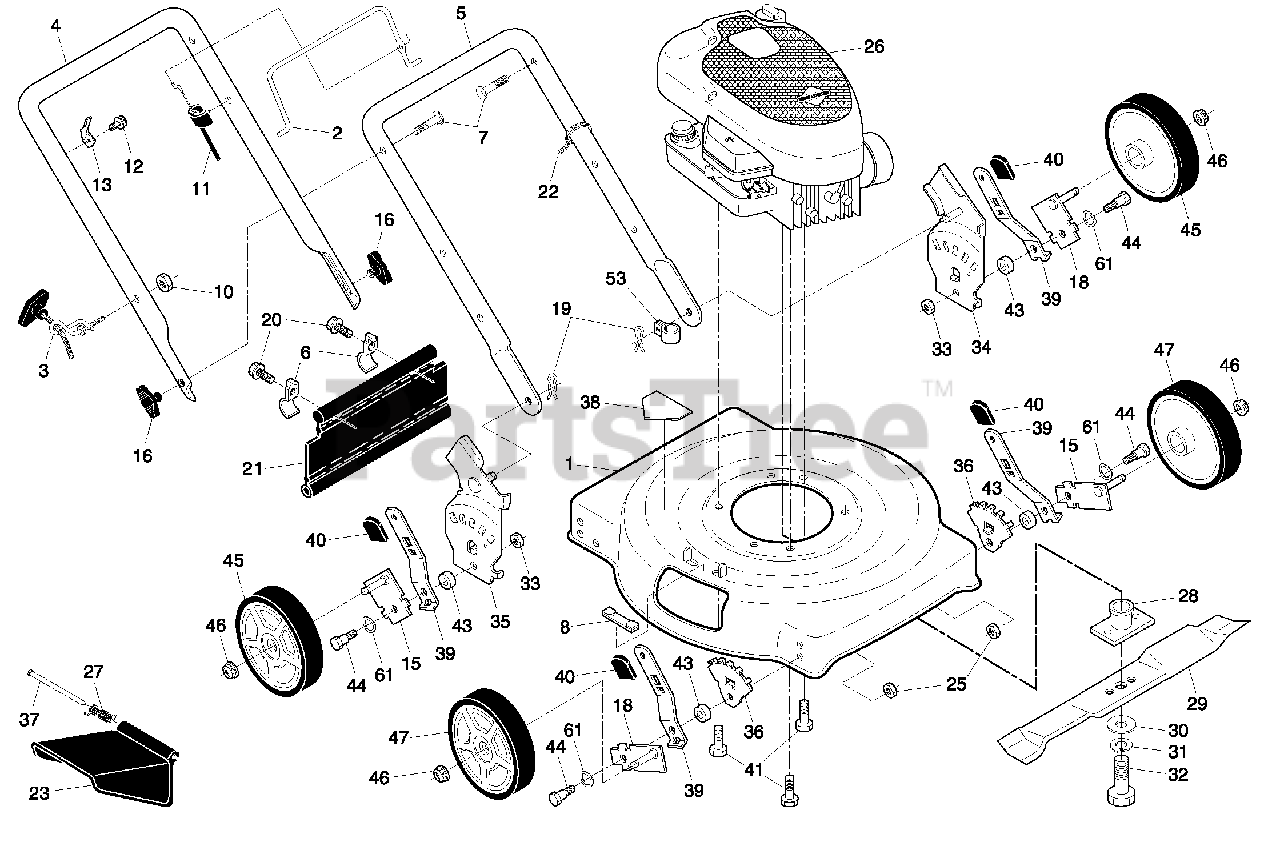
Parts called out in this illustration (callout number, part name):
1	Kit, Housing
2	Control Bar
3	Rope Guide
4	Upper Handle
5	Lower Handle
6	Shoulder Bolt 5/16-18 x 1/2
7	Handle Bolt 5/16-18
8	Clip, Closeout
10	Locknut, Hex 1/4-20
11	Engine Zone Control Cable
12	Screw, Hex Head, Threaded, Rolled #10-24 x 1/2
13	Up-Stop Bracket
15	Axle Arm Assembly, Left Front & Right Rear
16	Handle Knob
18	Axle Arm Assembly, Right Front & Left Rear
19	Hairpin Cotter
20	Screw, Tapping, Hex Washer Head #10-24
21	Rear Skirt
22	Wire Tie
23	Discharge Guard
25	Nut, Hex, Flangelock 5/16-18
27	Torsion Spring
28	Blade Adapter
29	22" Blade
30	Hardened Washer
31	Helical Lockwasher 3/8
32	Screw, Hex Head, Grade 8, 3/8-24 x 1-3/8
33	Nut, Hex, Flangelock 5/16-18
34	Wheel Bracket Support (Left)
35	Wheel Bracket Support (Right)
36	Wheel Bracket Adjuster
37	Hinge Rod
38	Danger Decal
39	Selector Spring
40	Selector Knob
41	Screw, Hex Head, Threaded, Rolled 3/8-16 x 1
43	Spacer
44	Shoulder Bolt 5/16-18 x .33
45	Wheel & Tire Assembly, Rear
46	Nut, Hex, Flangelock 3/8-16
47	Wheel & Tire Assembly, Front
53	Clip, Cable
61	Washer, Curved, Cylindrical
61	Operator's Manual, English
61	Operator's Manual, French
61	Repair Parts Manual
